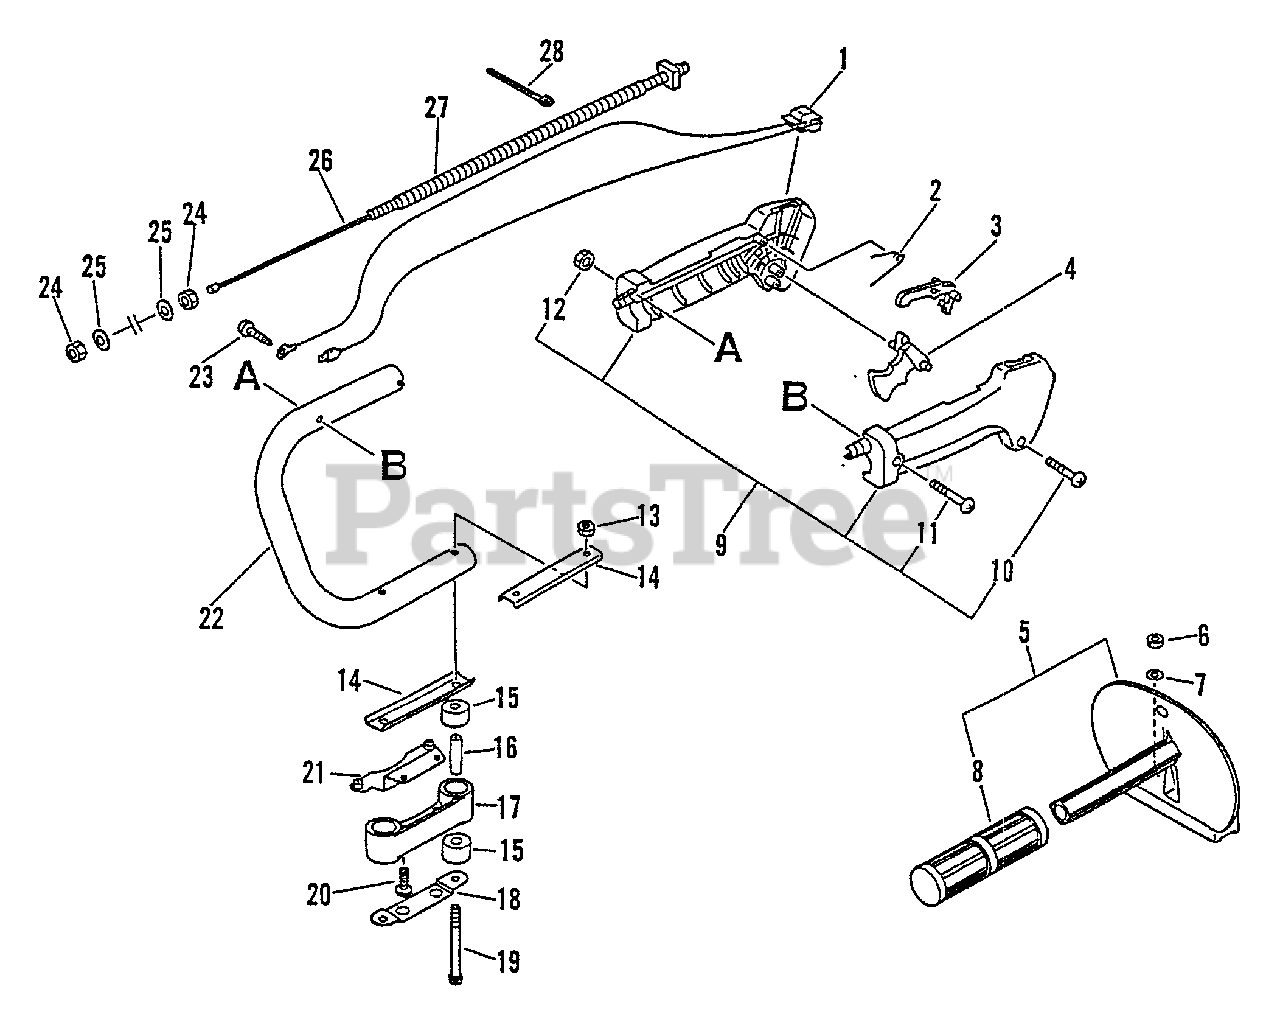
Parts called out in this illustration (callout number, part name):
1	IGNITION SWITCH ASSY
2	SPRING, LOCKOUT LEVER
3	LOCKOUT, THROTTLE
4	TRIGGER, THROTTLE
5	HANDLE ASSY - FRONT
7	WASHER - 6
8	GRIP, HANDLE
9	THROTTLE CONTROL ASSY
10	SCREW - 3X25
11	SCREW - 5X30
13	LOCKNUT - 5
14	BRACKET, HANDLE - LOWER
16	SPACER
17	BRACKET, HANDLE
18	PLATE, CUSHION
19	SCREW - 5X60
20	SCREW - 5X16
22	HANDLE - REAR
23	SCREW - 5X10
25	WASHER - 6
26	CABLE, THROTTLE
28	TIE, CABLE
